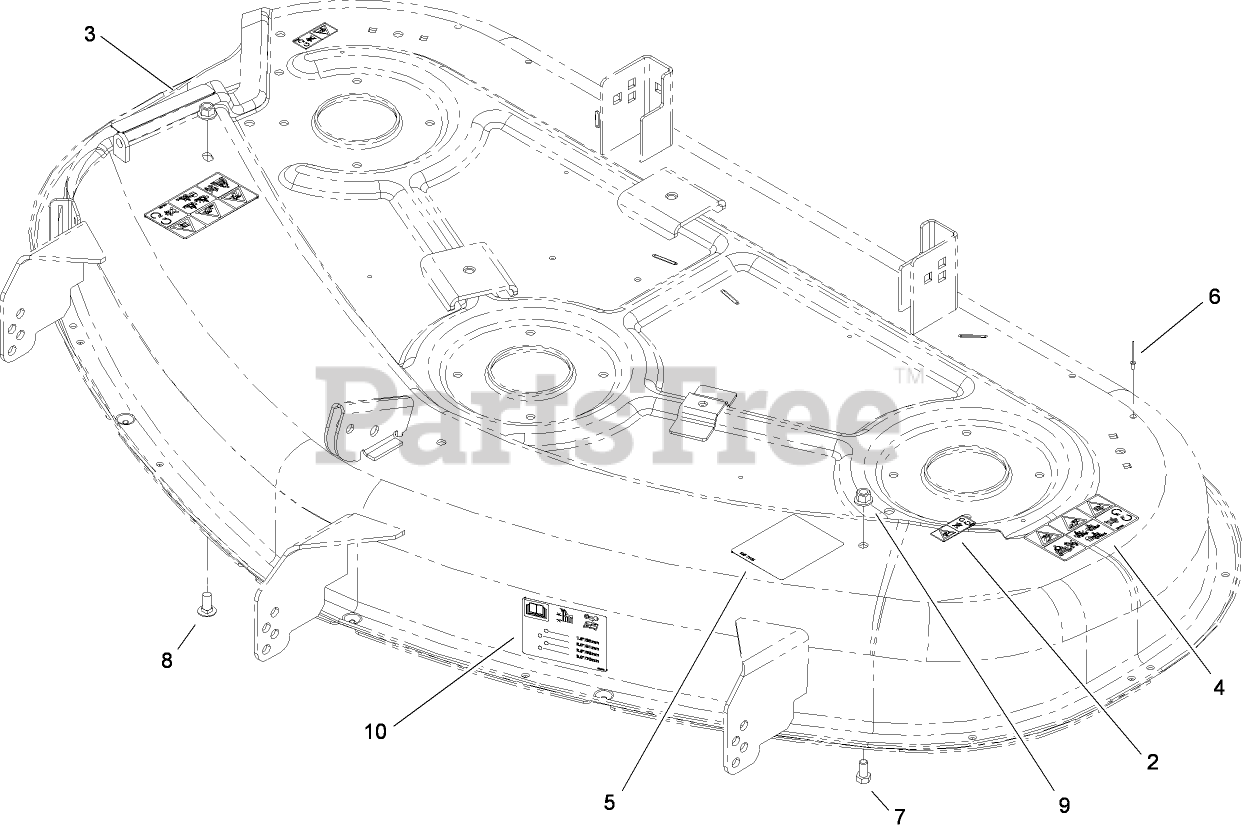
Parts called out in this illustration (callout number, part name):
2	DECAL-DANGER
3	DECAL-DANGER
4	DECAL-DANGER
5	DECAL-ROUTING, BELT
6	RIVET-BLIND
7	SCREW-HH
8	SCREW-CARR
9	NUT-LOCK, NI
10	DECAL-SCALP, ANTI
